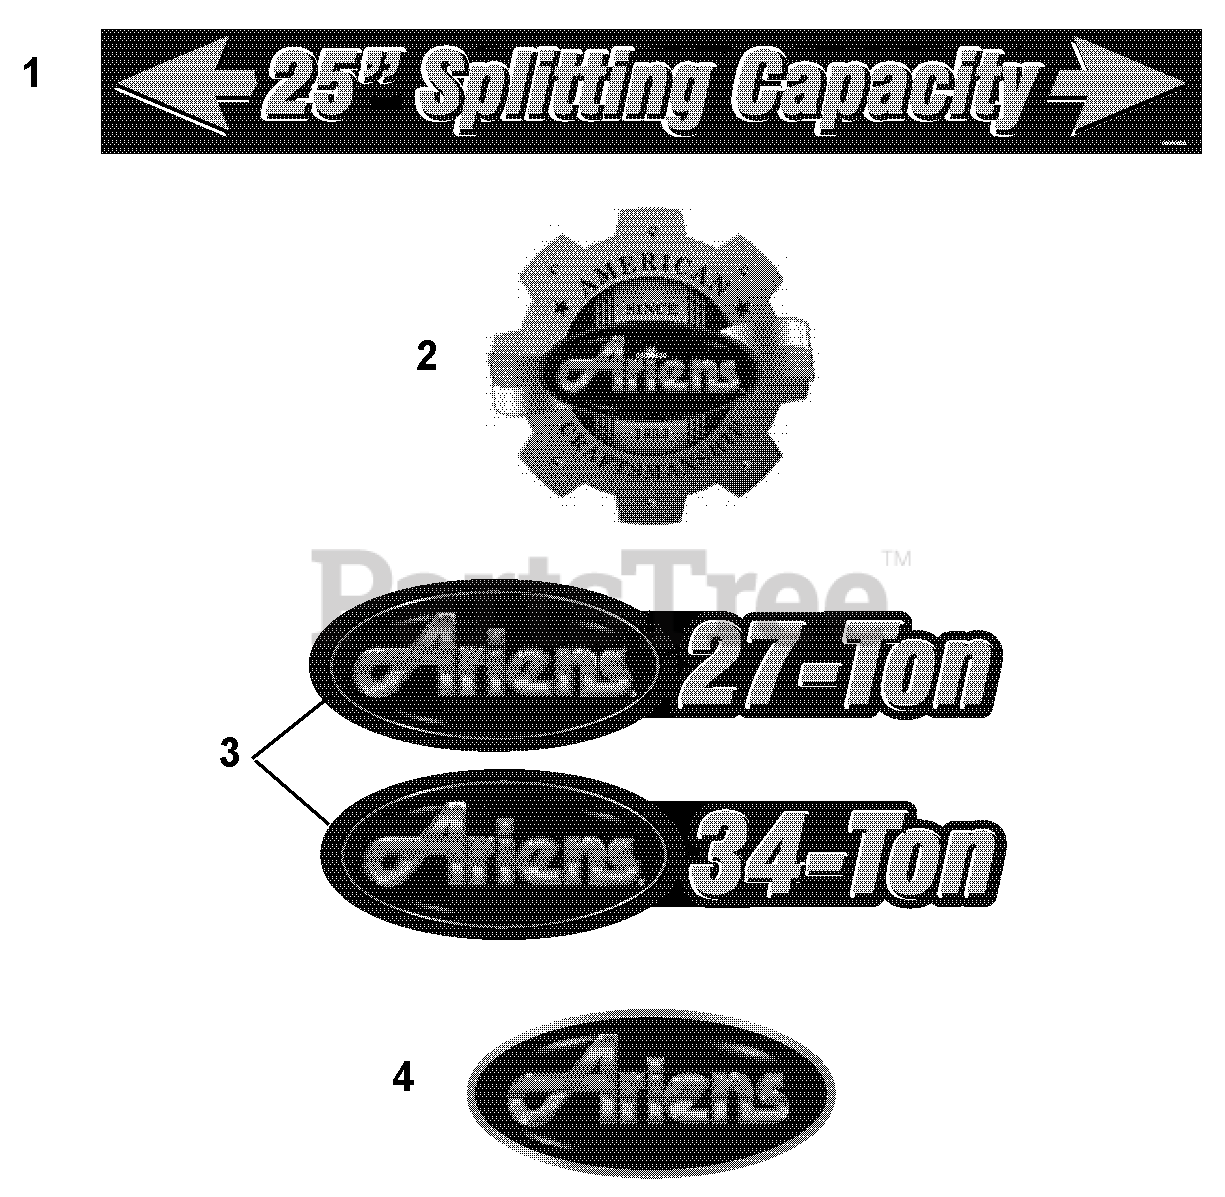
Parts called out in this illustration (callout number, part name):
1	DECAL, 25"SPLIT CAP
2	Decal, Ariens
3	DECAL, 27TON/ARIENS LOGO
3	DECAL, 34TON/ARIENS LOGO
4	DECAL, ARIENS JEWEL (LARGE)
